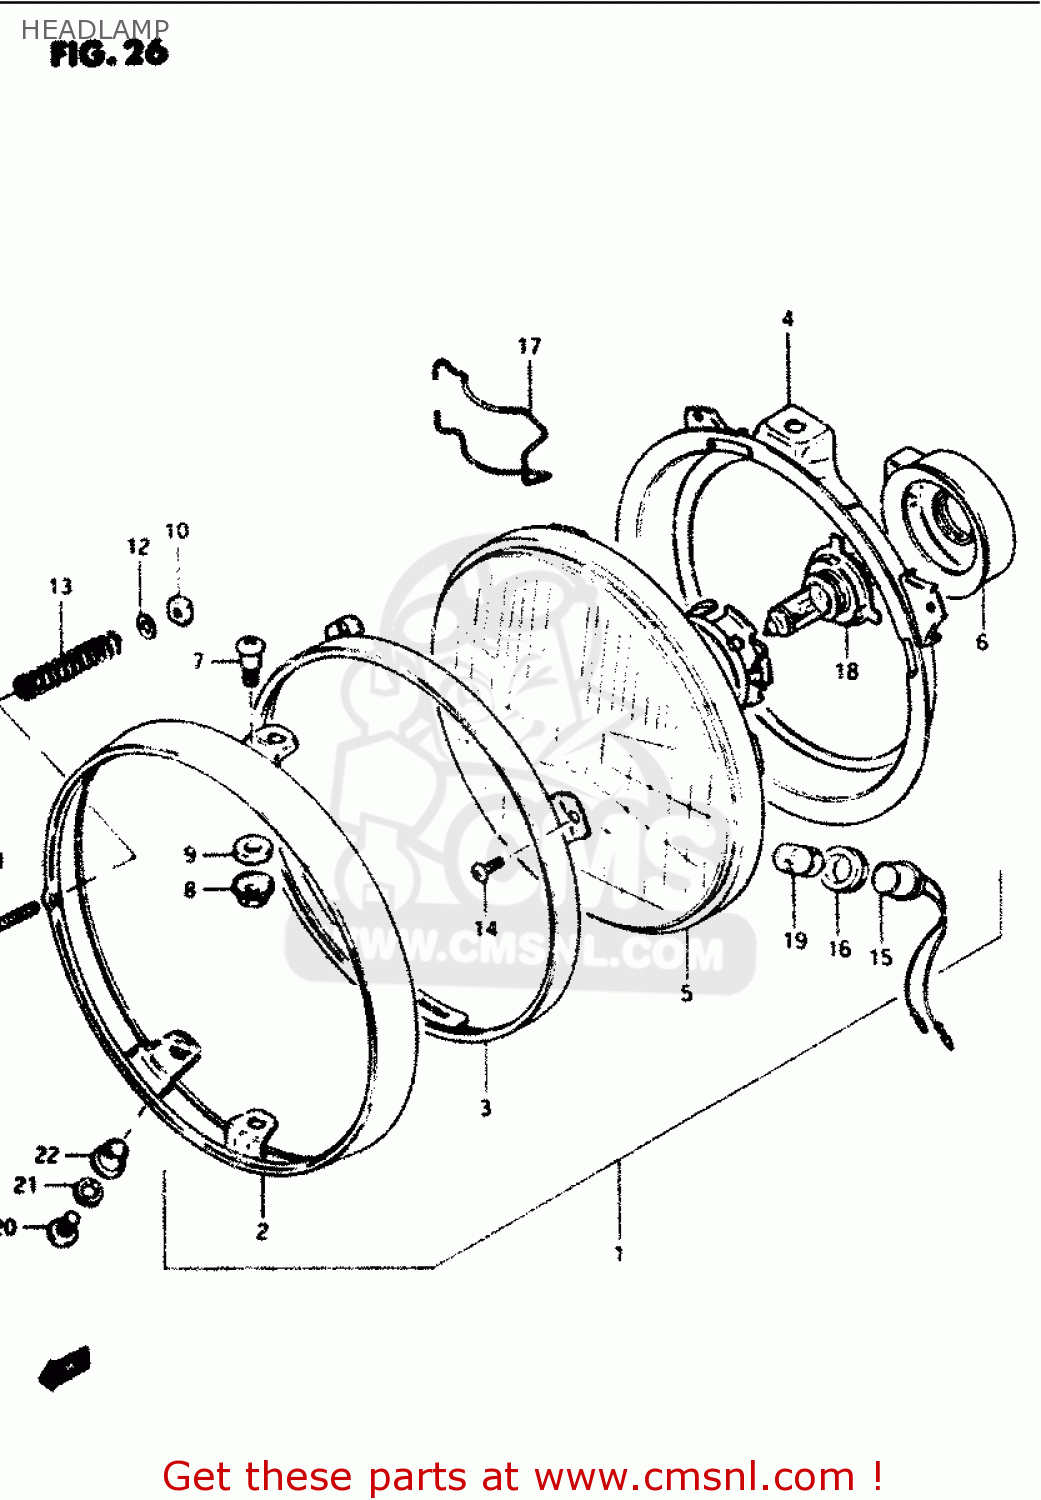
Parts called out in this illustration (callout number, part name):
1	HEADLAMP ASSY
2	RIM
3	RETAINER
4	RING,HEADLAMP UNIT
5	UNIT
6	COVER,HEADLAMP SOCKET
7	SCREW
8	NUT,ADJUSTING
9	SPACER
10	NUT
11	SCREW
12	WASHER
13	SPRING,HEADLAMP ADJUST
14	SCREW
15	SOCKET
16	JOINT,RUBBER
17	CLAMP,HEADLAMP SOCKET
18	BULB(12V60/55W,H4)
19	BULB(12V4W)
20	SCREW
21	WASHER,LOCK
22	WASHER
